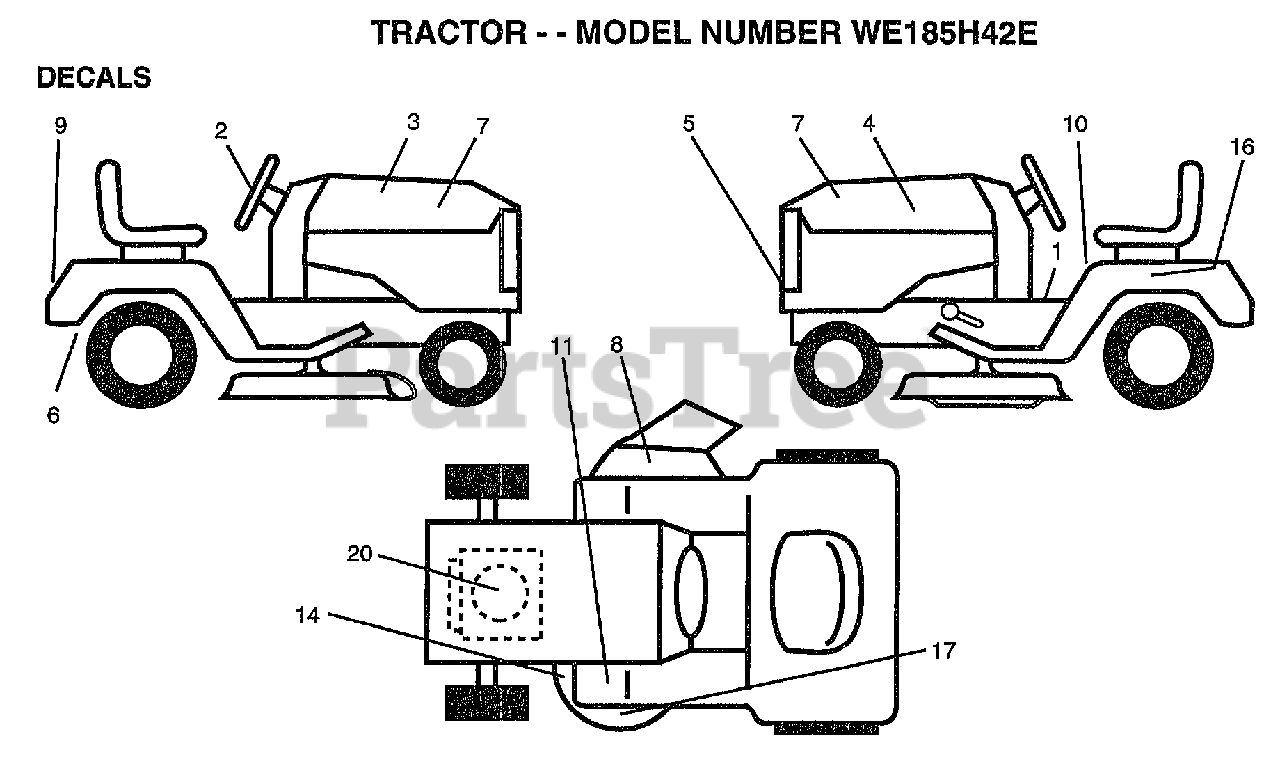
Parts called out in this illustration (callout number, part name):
1	DECAL SADDLE OPER
2	DECAL, INS STRG WH
3	DECAL.HOOD.RH.
4	DECAL.HOOD.LH
5	DECAL, GRILLE LENS
6	DECAL DRAWBAR LH
7	DECAL.PANEL.SIDE
8	"DECAL, WARNING"
9	DECAL.FENDER.LOGO
10	DECAL.CAUT.ENG/FR
11	DECAL T
14	"DECAL-SCHEM,BELT"
16	DECAL.BATRY.3-3908
17	DECAL, DECK GRASSEATER
20	DECAL.HP.ENGINE
